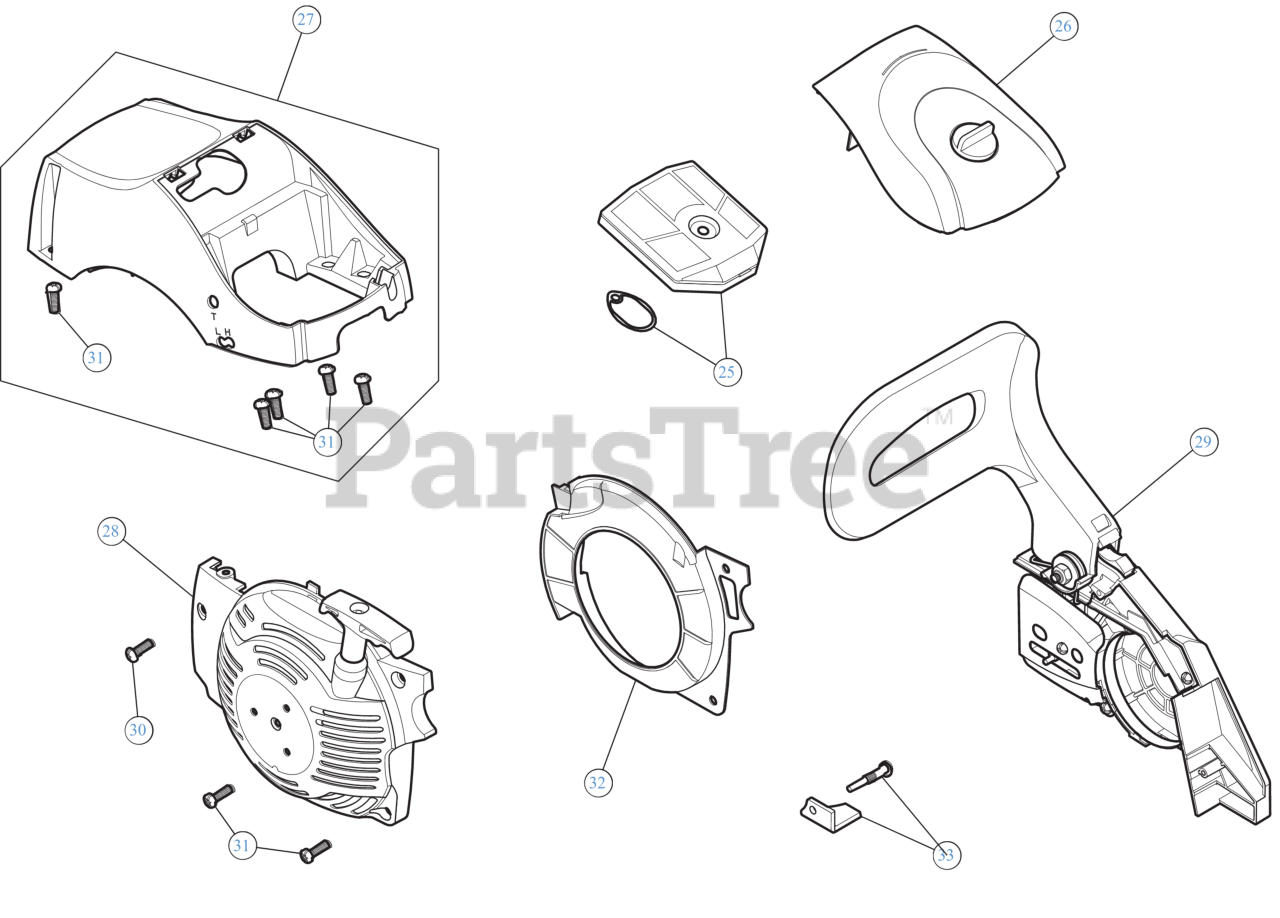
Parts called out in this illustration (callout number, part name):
23	THROTTLE ROD
24	FUEL FILTER
25	AIR FILTER
26	AIR FILTER COVER
27	CYLINDER COVER
28	STARTER HOUSING
32	BAFFLE
33	CHAIN CATCHER
